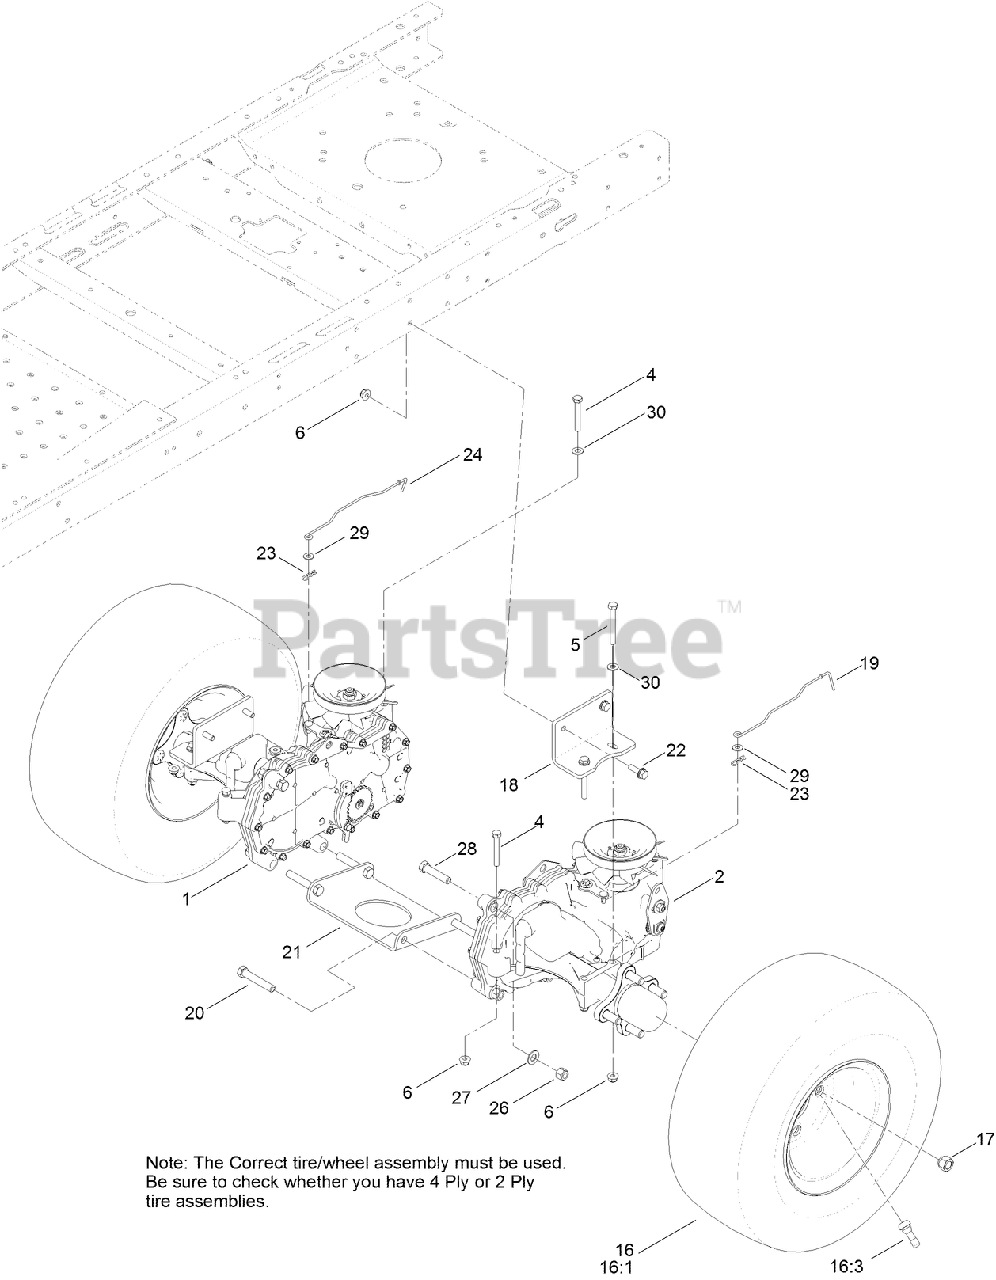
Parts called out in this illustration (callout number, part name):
1	RH HYDRO TRANSAXLE ASM
2	LH HYDRO TRANSAXLE ASM
4	SCREW-HH
5	SCREW-HH
6	NUT-HF, NI
16	4 PLY WHEEL AND TIRE ASM
16	2 PLY TIRE AND WHEEL ASM
16:1	TIRE-4 PLY
16:1	TIRE-2PLY
17	NUT-LUG
18	MOUNT-HYDRO
19	ROD-BYPASS, LH
20	SCREW-HH
21	PLATE-CROSS, HYDRO
22	SCREW-HHF
24	ROD-BYPASS, RH
26	NUT-LOCK, NI
27	WASHER-FLAT
28	SCREW-HH
29	WASHER
30	WASHER-PLAIN
